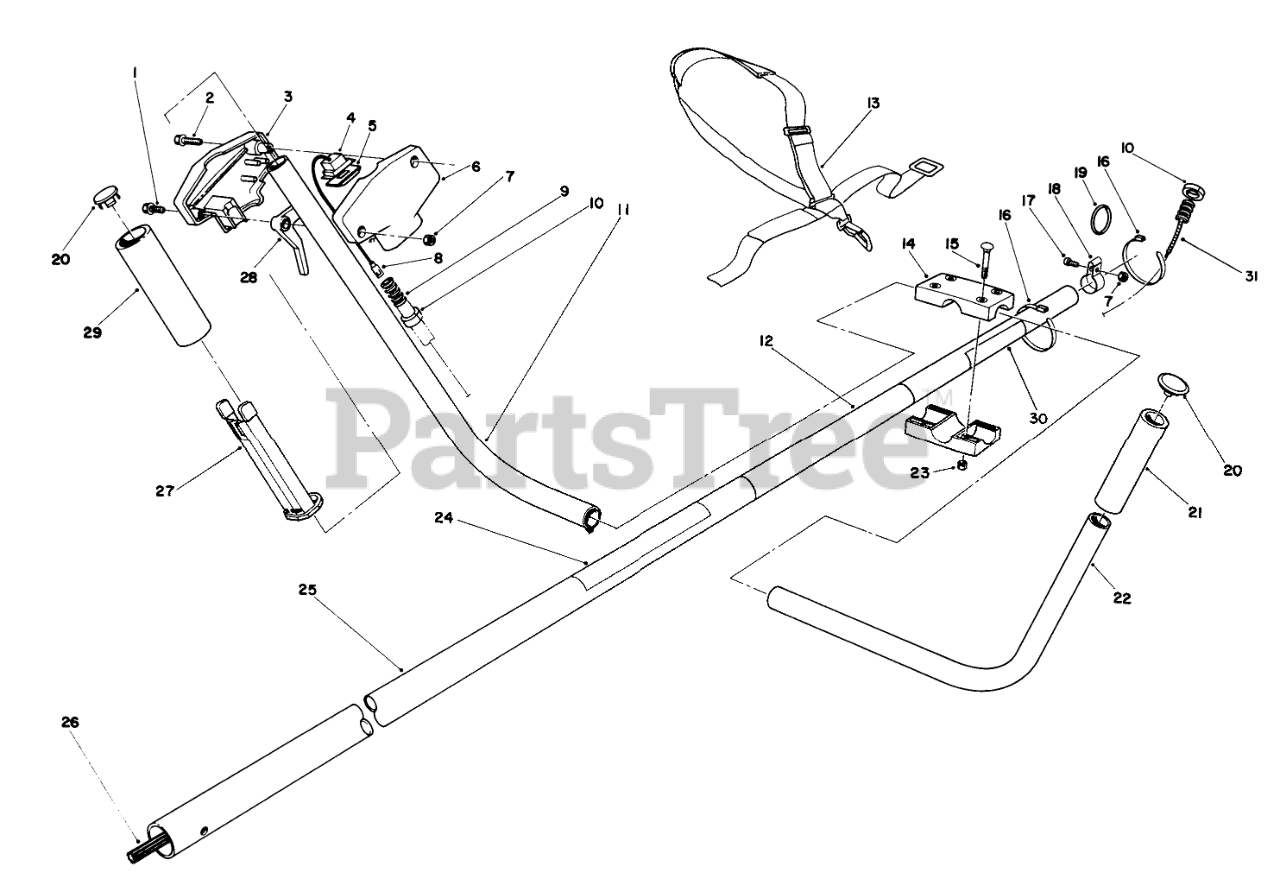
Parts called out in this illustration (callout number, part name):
1	SCREW-SHOULDER
3	RH HOUSING
4	SWITCH
5	SWITCH COVER
6	LH HOUSING
7	NUT-LOCK, NI
8	WIRE ASM
9	Cover-Cable
10	RING FITTING
11	RH HANDLE
12	DECAL - WARNING
13	Deluxe Harness
14	CLAMP
15	SCREW-CARR
16	TIE-CABLE
17	SCREW-SRH
18	HARNESS CLAMP
19	RING-HARNESS
20	TUBE CLOSURE
21	FOAM GRIP
22	LH HANDLE
23	NUT-LOCK, NI
24	Decal-TC 5010
25	TUBE ASM
26	SPLINE SHAFT
27	TROUGH
28	THROTTLE LEVER
29	GRIP-RUBBER
30	DECAL-INSTRUCTION
31	THROTTLE CABLE
